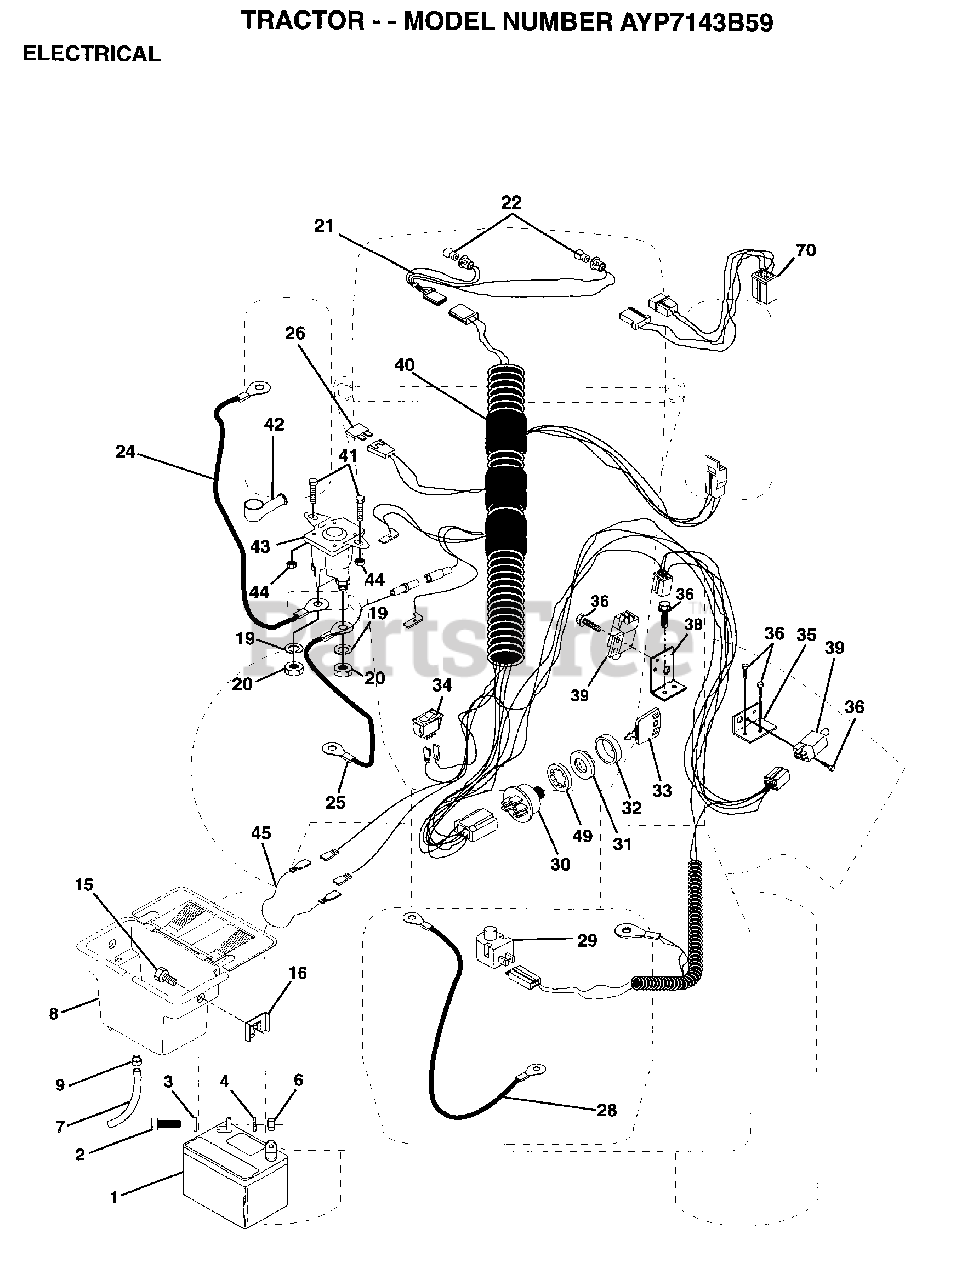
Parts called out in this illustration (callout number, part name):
2	BOLT LT
3	WASHER
4	LOCKWASHER
7	TUBE T
9	HOSE CLAMP T
15	SCREW.CAP.HEX.NYL
16	NUT.CLIP.FASTNER
21	"HARNESS,LIGHT SOC"
22	NUT
22	HEADLAMP BULB
24	"CABLE T, BATTERY"
25	CABLE.BTRY.6GA.RD
26	FUSE HYT
28	CABLE T
29	SWITCH SEAT
32	COVER KEY SWITCH
33	KEY STEEL DELTA
34	SWITCH LT
35	BRACKET LT
36	SCREW
38	BRACKET SWITCH IN
39	SWITCH INTERLOCKT
40	HARNESS.IGN.DASH.
41	BOLT.HX.1/4-20
44	NUT
45	ADAPTER AMMETER
49	LOCKWASHER
70	HARNESS.ENG.DUAL
